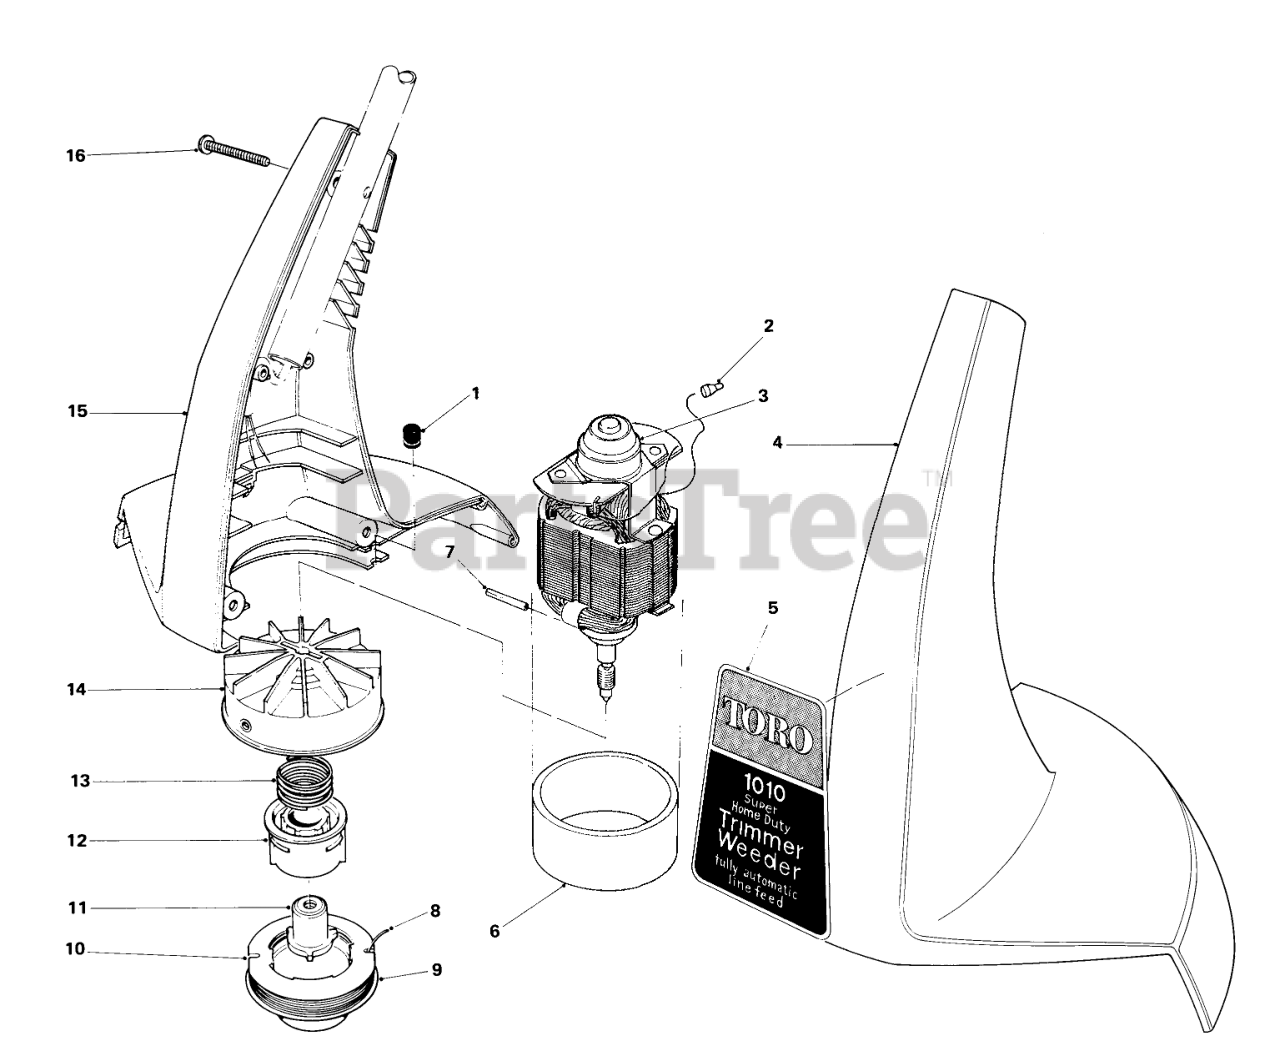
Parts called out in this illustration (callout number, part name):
1	GROMMET
2	CONNECTOR WIRE JOINT
3	Motor
4	Housing-L.H.
5	Decal-Housing
6	DAMPENING SLEEVE
7	COIL PIN
8	Filament Line 30-(.050 Dia.)
9	SPOOL CAP
10	Prewound Spool Cap
11	DRIVER DETENT
12	CORE - SPOOL
13	SPRING-COMPRESSION
14	FAN HUB ASM
15	Housing Assembly, R.H.
16	Screw
